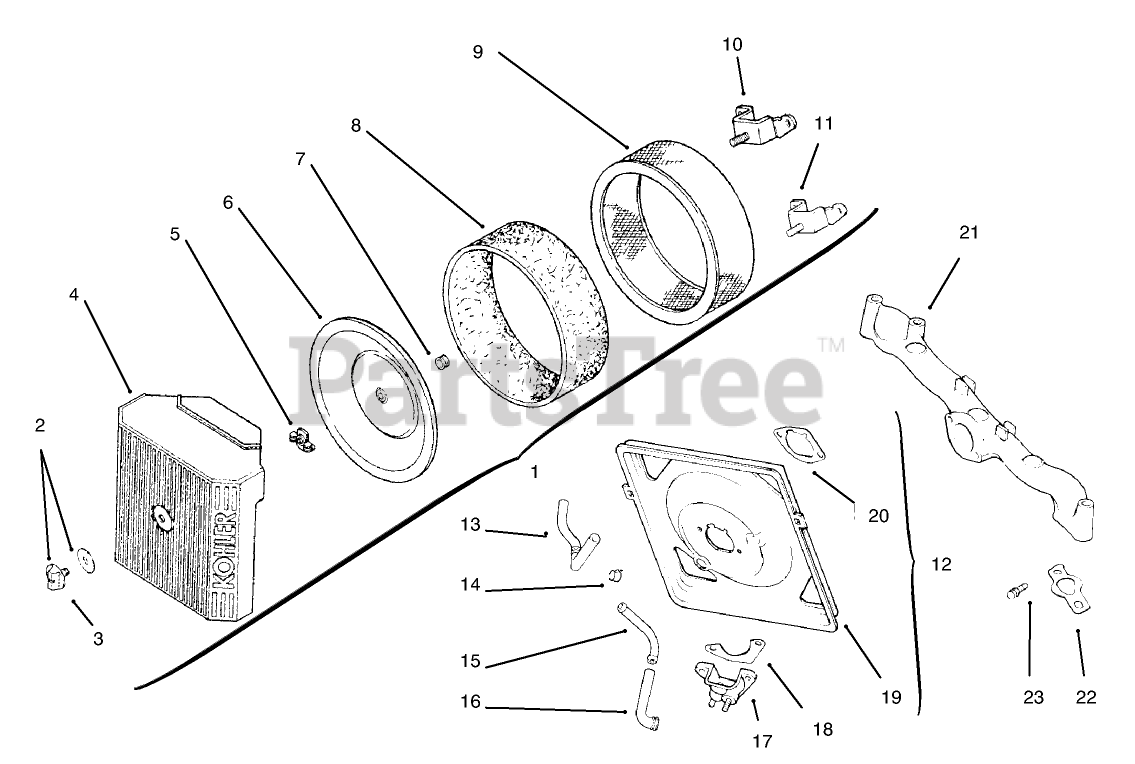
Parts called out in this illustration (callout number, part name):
1	Kit-Air Cleaner Cover
2	Kit-Knob w/Gasket
3	Knob-Cover
4	Cover-Air Cleaner
5	Nut-Wing
6	Cover-Inner Air Cleaner
7	Seal-Air Intake (Only On: 72103)
8	Element-Precleaner
9	Element-Air Cleaner
10	Bracket-Air Cleaner
11	Bracket-Air Cleaner
12	Kit-Air Cleaner Base
13	Hose-Breather
14	Clamp
15	Fitting
16	Hose-Breather
17	Cup-Fuel Spitback
18	Gasket-Fuel Spitback Cup (Only On: 72103, 72083)
19	Base-Air Cleaner
20	Gasket-A/C Base (Only On: 72103, 72083)
21	Manifold-Intake (Only On: 72103)
22	Gasket-Intake Manifold
23	Screw
